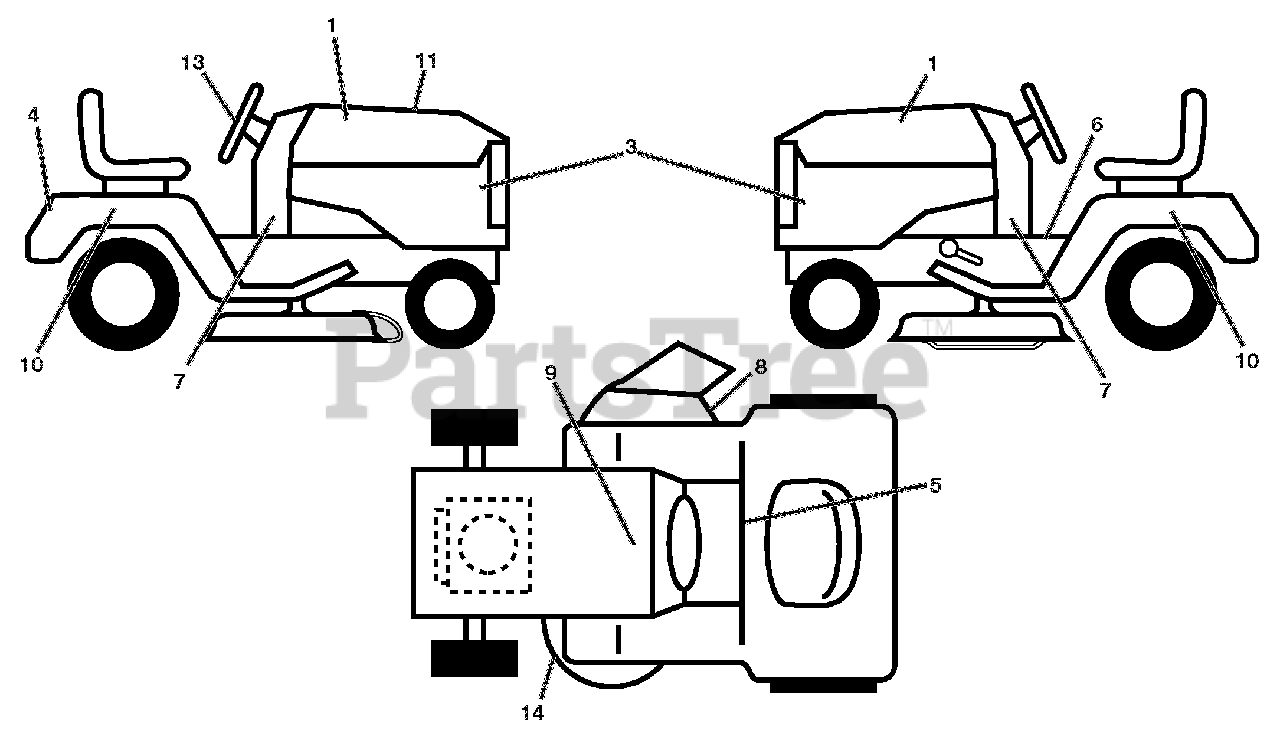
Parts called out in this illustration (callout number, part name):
1	DECAL.HOOD.RH.PRECISION.ARIENS
3	DECAL.SDPNL.PWRDBY KOHL.ARIENS
4	DECAL.FENDER.REAR.ARIENS
5	Decal, Flag
6	DECAL.FENDER.WARNING.ENG/FR.07
7	DECAL DASH LOWER
8	DECAL.MOWER.WARN.KEEP HAND AWY
9	DECAL.BAT.DAN/POI P/L SYM.WPN
10	DECAL.FENDER.SIDE.HYDRO.ARIENS
11	DECAL REPLACEMENT
13	DECAL.WHEEL.STEER.ARIENS
14	DECAL.V-BELT.SCH.42/46"MEC/ELE
